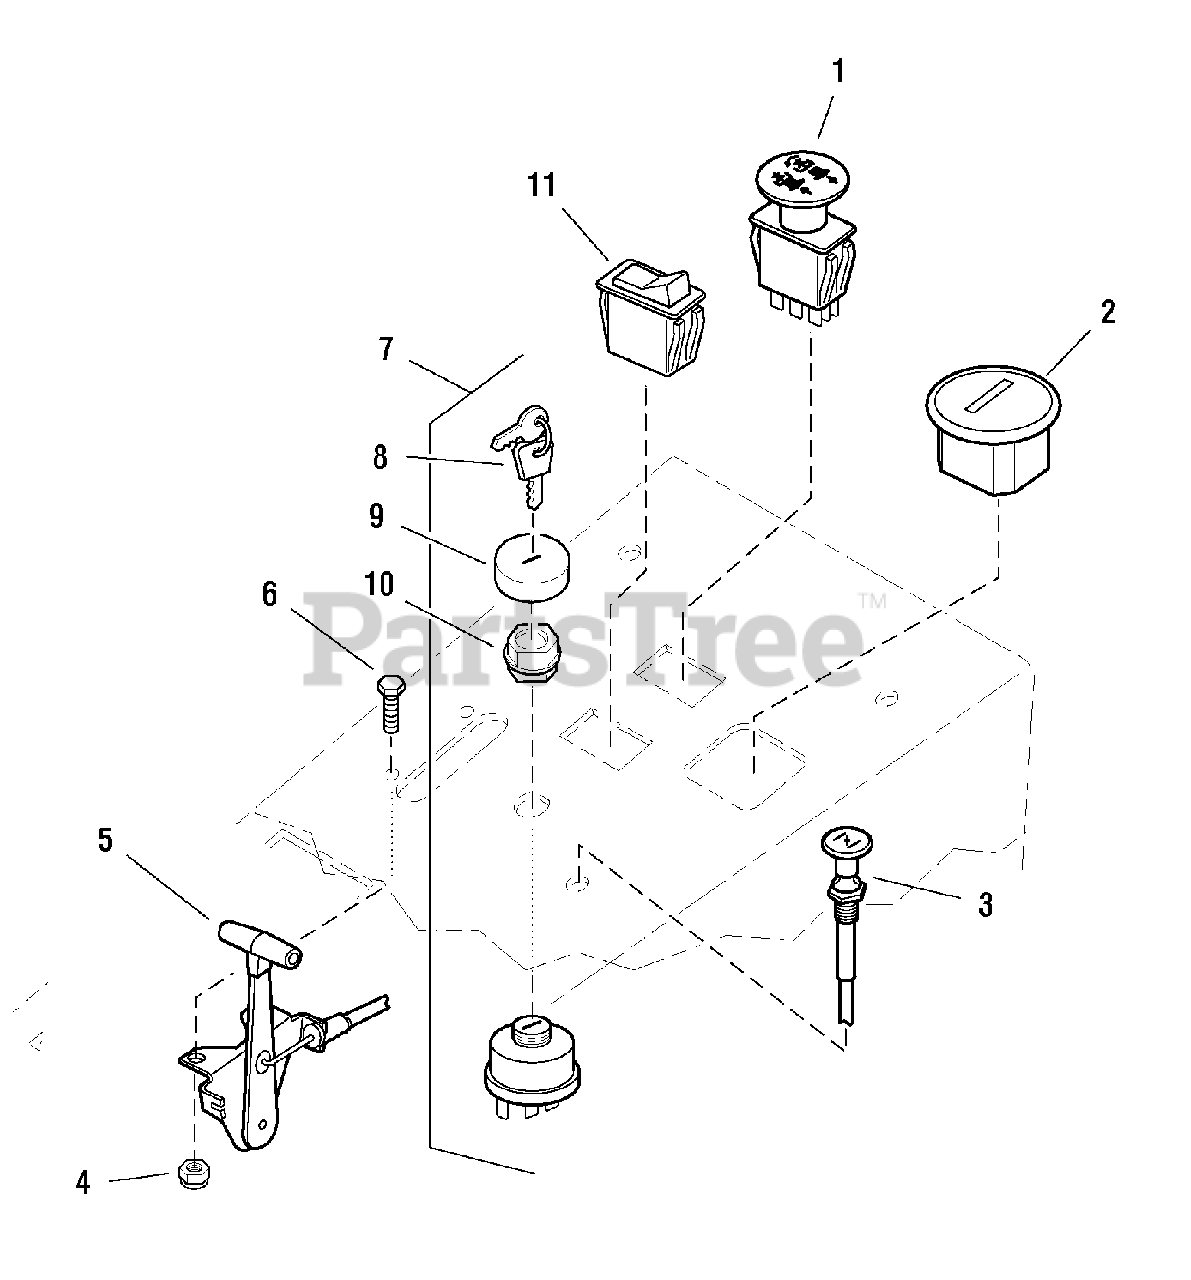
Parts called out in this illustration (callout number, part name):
1	SWITCH, PTO
3	CABLE, Choke Control
4	NUT, Hex, Nylon Lock, 1/4-20
5	CABLE, Throttle Control
6	CAPSCREW, Hex Hd, 1/4-20 x 3/4
7	SWITCH, Ignition, Complete
8	KEY, Ignition, Molded
10	PLASTIC NUT
11	SWITCH, Headlight
